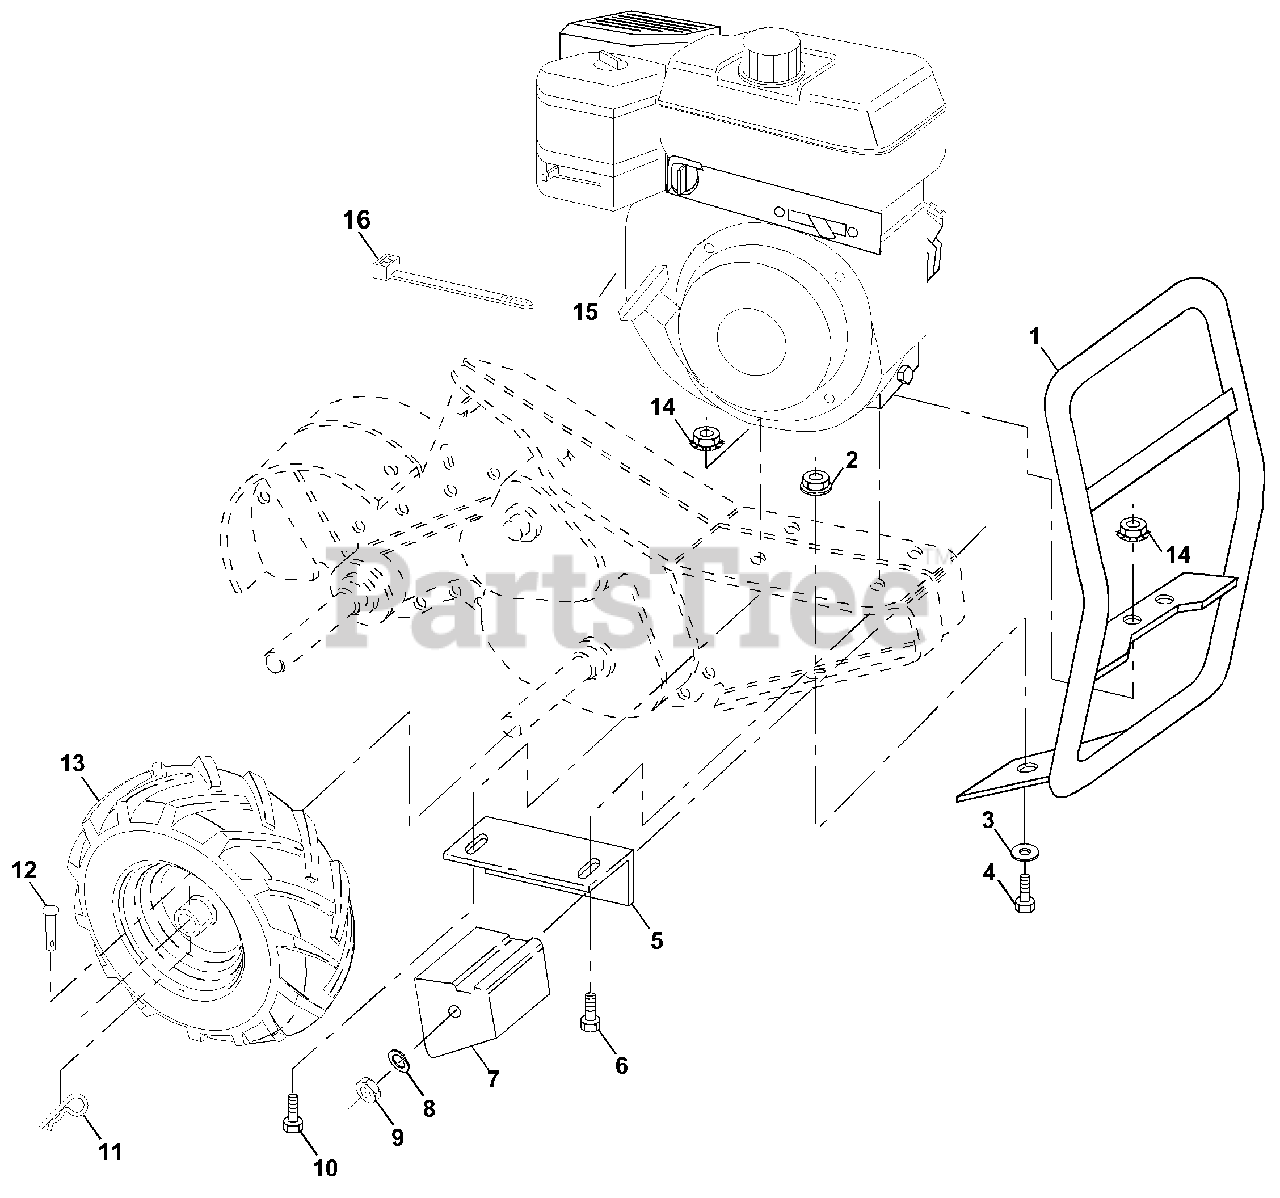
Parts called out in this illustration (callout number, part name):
1	Bumper
2	Locknut, Hex, Flange 5/16-18
3	Washer 11/32 x 11/16 x 16 Ga.
4	Bolt, Hex 5/16-18 x 3/4
5	Bracket, Reinforcement
6	Bolt, Hex 5/16-18 x 2
7	Counter Weight, R.H.
8	Washer, Lock 3/8
9	Nut, Hex 3/8-16
10	Bolt, Hex 5/16-18 x 1-1/2
11	Clip, Hairpin
12	Rivet, Drilled
13	Tire
13	Rim
13	Tire Valve
14	Nut, Keps 5/16-18
